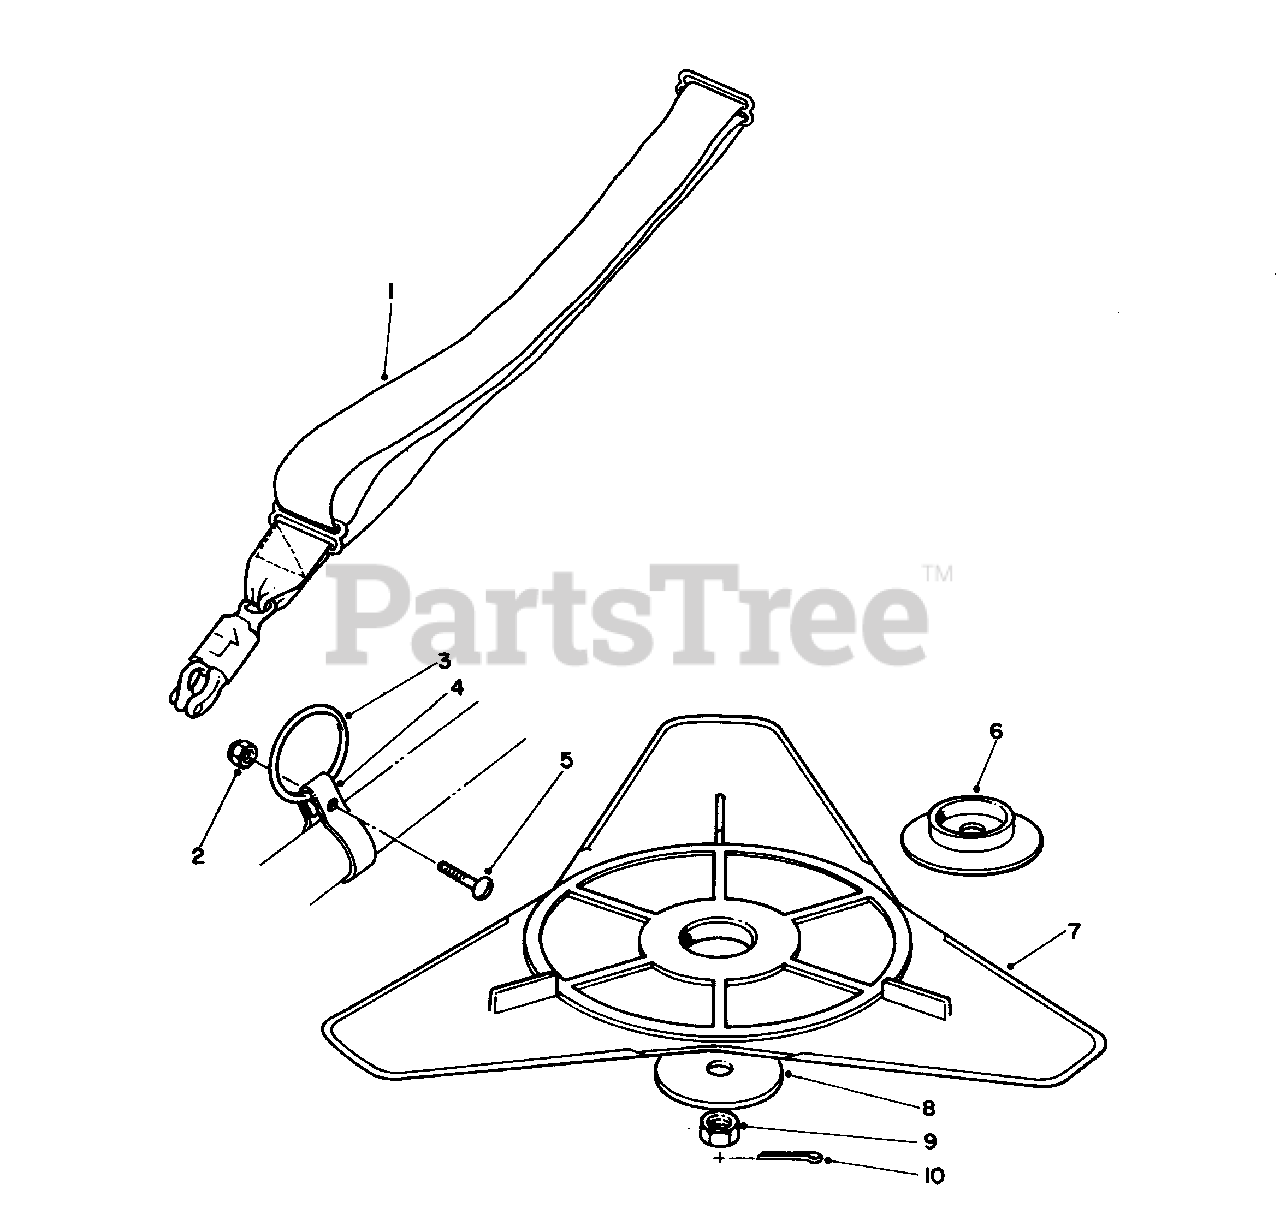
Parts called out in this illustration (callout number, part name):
1	Standard Harness
3	Ring
4	Clamp
6	Plate, Blade Adapter
8	Washer Plate
10	Cotter Pin
